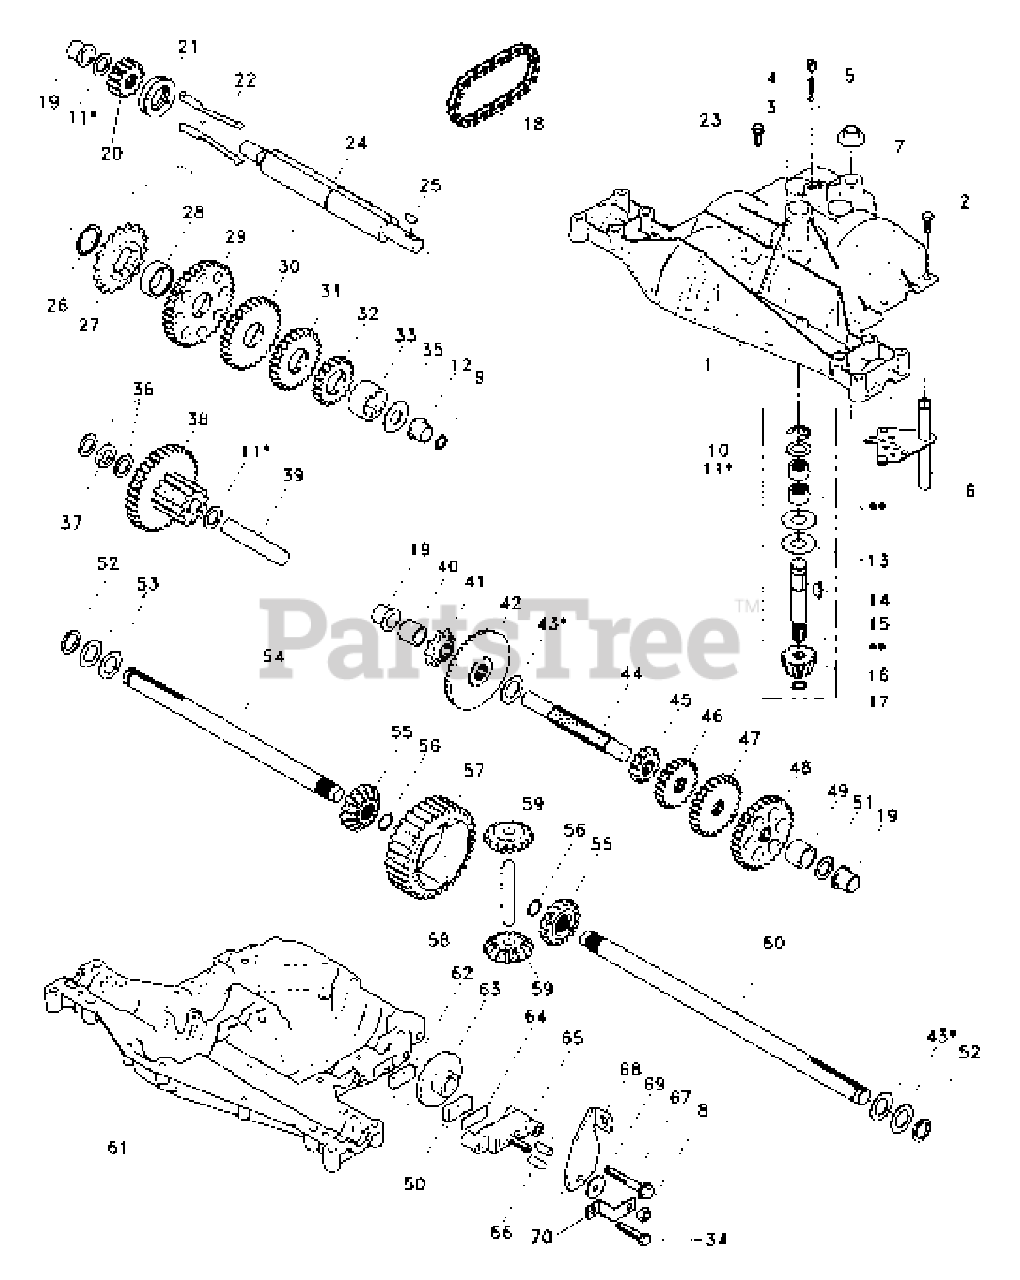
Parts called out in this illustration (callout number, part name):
1	Housing, Upper
2	Screw, Self-Tapping, Large 1/4-20 x .734
3	Ball, Detent
4	Spring, Detent
5	Screw, Set
6	Kit, Shifter Assembly
7	Boot, Shifter
8	Locknut 5/16-24
10	Ring, Retaining
11	Assembly, Kit, Shim .625 Shaft
12	Bearing, Flange
13	Washer, Plain .632 x 1.38 x .046
14	Key, Woodruff, #9
15	Assembly, Kit, Input Shaft
16	Pinion, Bevel, 14 Teeth
17	Ring, Retaining
18	Chain, 24 Pitches
19	Bearing, Flange
20	Gear, Spur, 14 Teeth
21	Collar, Clutch
22	Assembly, Kit, Clutch Keys
23	Screw, Self-Tapping, with Sealer
24	Shaft, Intermediate
25	Key, Woodruff, #61
26	Ring, Retaining
27	Sprocket, 18 Teeth
29	Gear, Spur, 37 Teeth
30	Gear, Spur, 30 Teeth
31	Gear, Spur, 25 Teeth
32	Gear, Spur, 19 Teeth
33	Spacer 1.133 x 1.50 x .750
34	Screw, Self-Tapping, Large 5/16-18 x 1.44
35	Washer, Plain .640 x 1.37 x .061
36	Washer, Plain .632 x 1.00 x .026
37	Spacer .630 x 1.00 x .169
38	Assembly, Gear, Combination of 12 Teeth and 35 Teeth
39	Shaft, Idler
40	Spacer .635 x .875 x .755
41	Sprocket, 9 Teeth
42	Gear, Bevel, 42 Teeth
43	Assembly, Kit, Shim .750 Shaft
44	Shaft, Drive
45	Gear, Spur, 12 Teeth
46	Gear, Spur, 20 Teeth
47	Gear, Spur, 25 Teeth
48	Gear, Spur, 31 Teeth
49	Spacer .781 x 1.00 x .750
50	Puck, Friction
51	Washer, Plain .632 x 1.00 x .060
52	Washer, Neoprene
53	Washer, Plain .758 x 1.25 x .031
54	Axle, L.H.
55	Gear, Miter, 15 Teeth
56	Ring, Retaining
57	Gear, Spur, 32 Teeth
58	Shaft, Cross
59	Gear, Miter, 15 Teeth
60	Axle, R.H.
61	Housing, Lower
62	Puck, Friction
63	Disc, Brake
65	Jaw, Brake
66	Pin, Dowel
67	Screw, Self-Tapping, Large 5/16-18 x 2.25
68	Lever, Actuating
69	Washer, Plain .321 x 1.00 x .055
70	Bracket, Anti-Rotation
71	Grease
